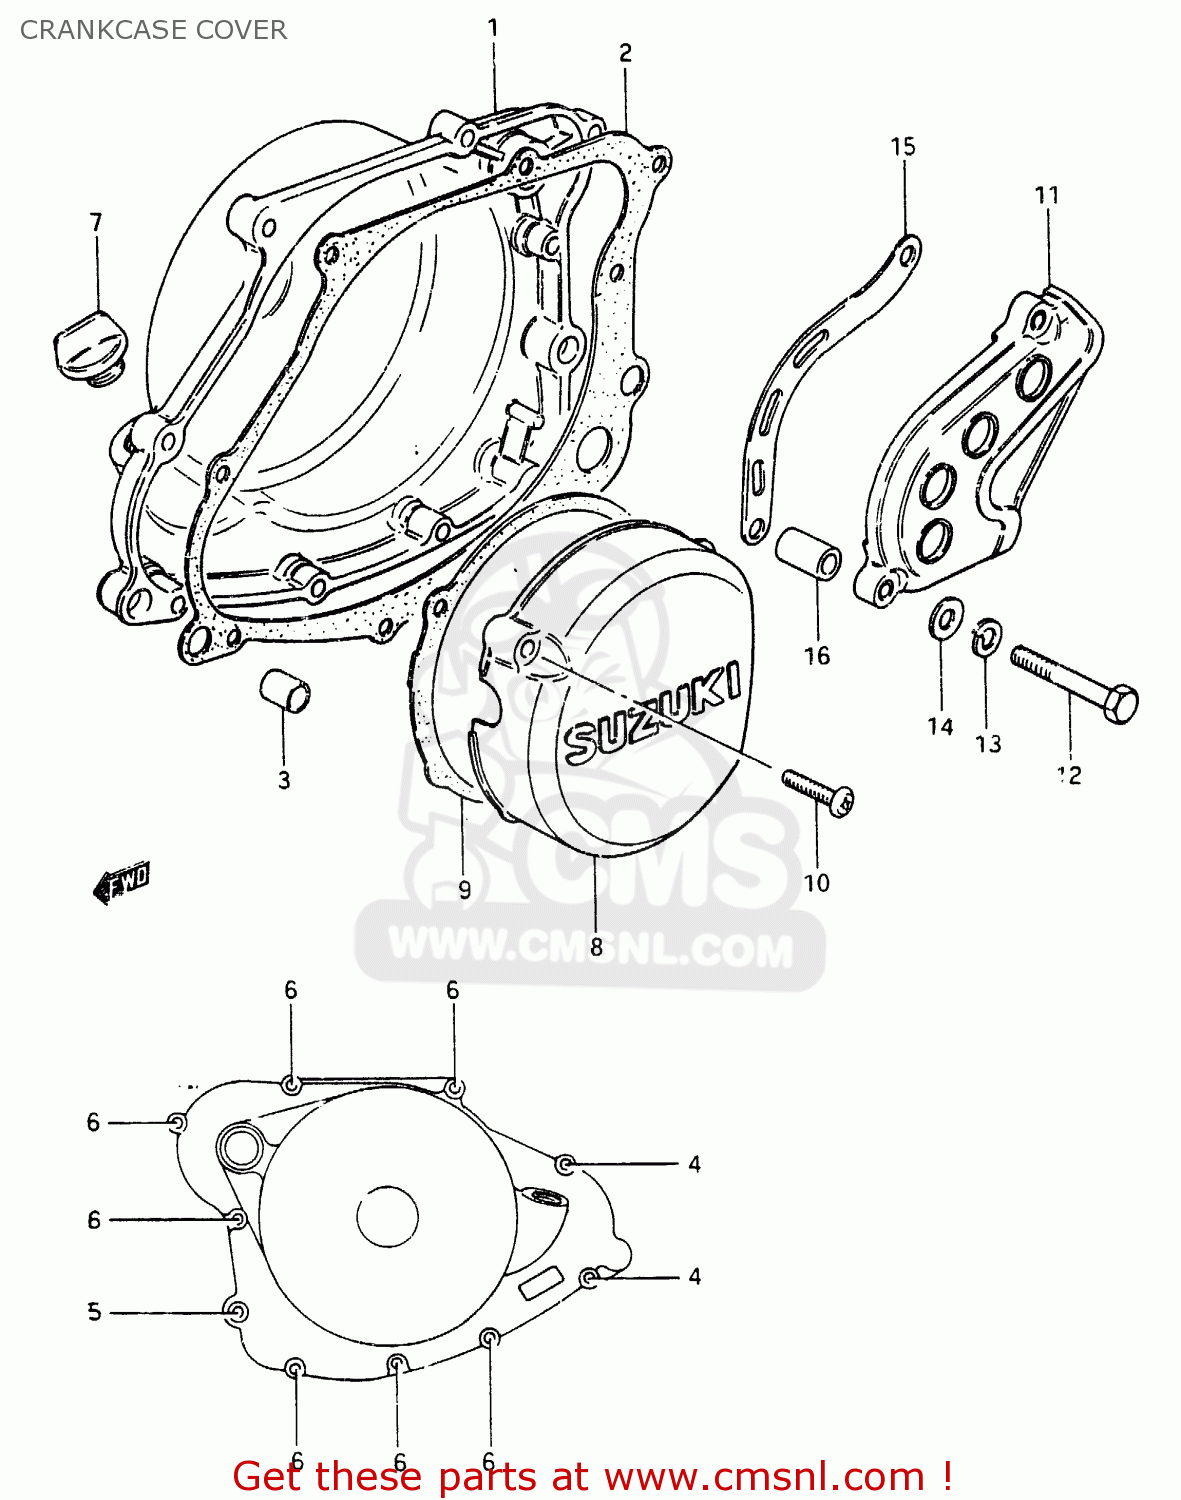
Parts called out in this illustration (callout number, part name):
1	COVER,CLUTCH
2	GASKET,CLUTCH COVER (MCA)
3	PIN
4	SCREW 6X30
5	SCREW (6X45)
6	SCREW
7	PLUG,OIL FILTER
8	COVER,MAGNETO
9	GASKET,MAGNETO COVER (MCA)
10	SCREW
11	COVER,ENGINE SPROCKET
12	BOLT 8X55
13	LOCK WASHER
14	WASHER
15	PLATE,FR CHAIN GUIDE
16	SPACER(8.6X16X24)
